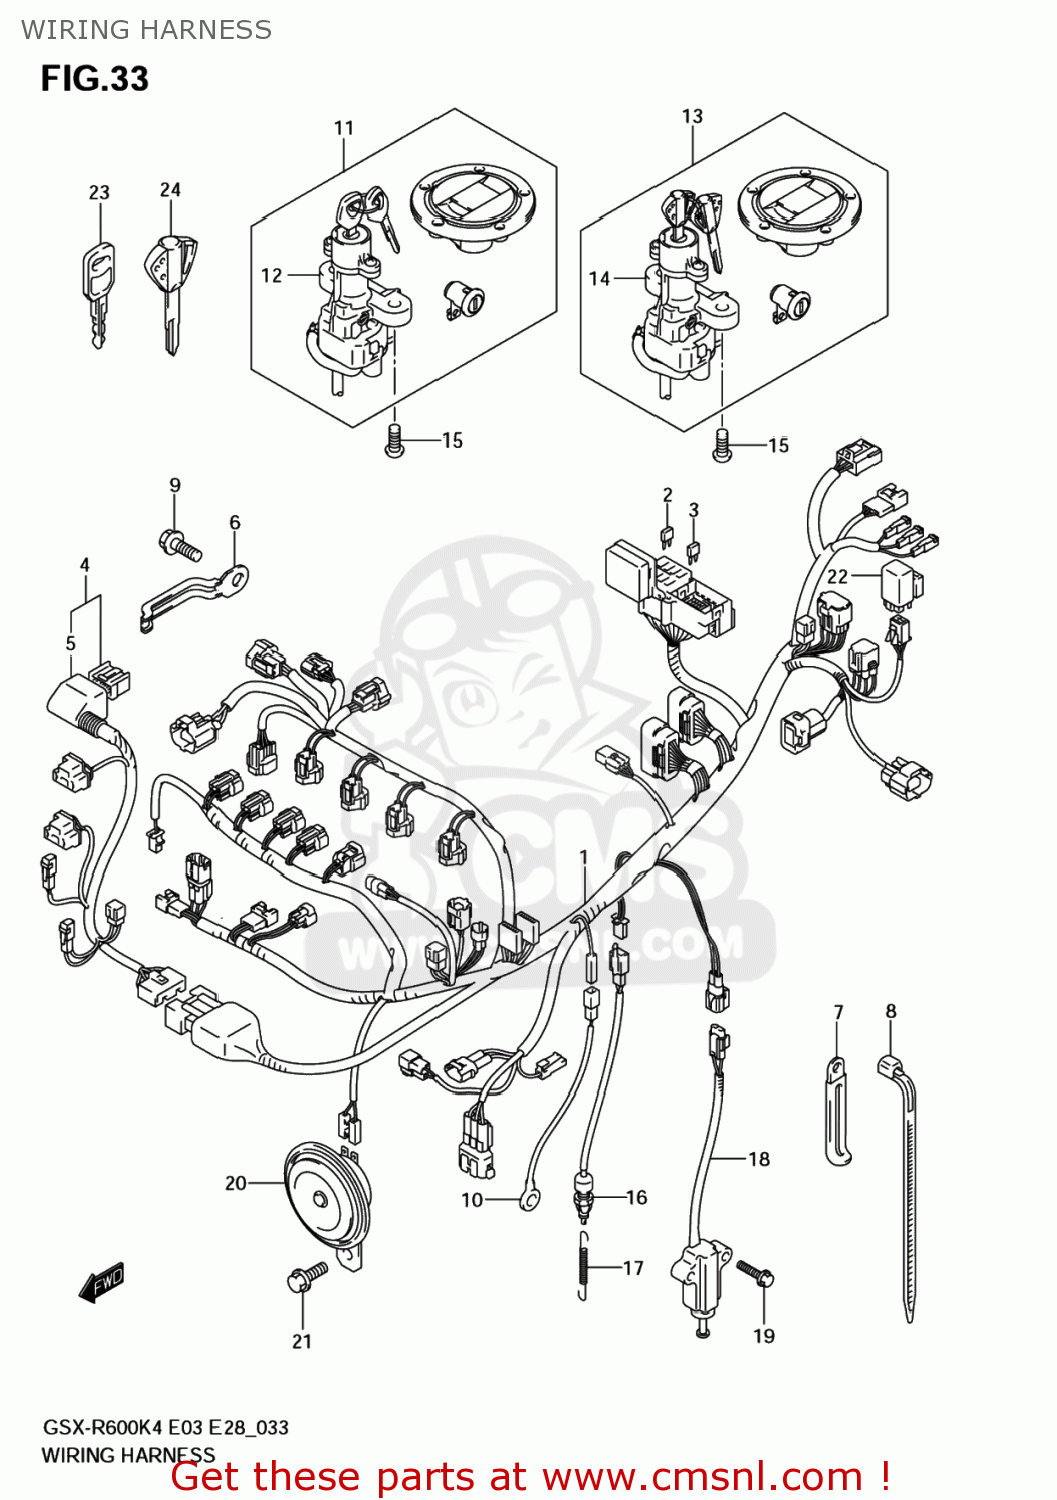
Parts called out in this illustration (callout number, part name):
1	HARNESS,WIRING NO.1
2	FUSE(10A)
3	FUSE(15A)
4	HARNESS,WIRING NO.2
5	COVER,SPEEDOMETER COUPLER
6	CLAMP
7	CLAMP(L:45)
8	CLAMP(L:95)
9	BOLT
10	WIRE,OIL PRESSURE SWITCH LEAD
11	LOCK SET
12	LOCK ASSY,STEE
13	LOCK SET
14	LOCK ASSY,STEERING
15	BOLT(8X20)
16	SWITCH ASSY,STOP LAMP
17	SPRING
18	SWITCH ASSY,SIDE STAND
19	BOLT
20	HORN ASSY
21	BOLT
22	RELAY ASSY
23	KEY,BLANK
24	KEY,BLANK
